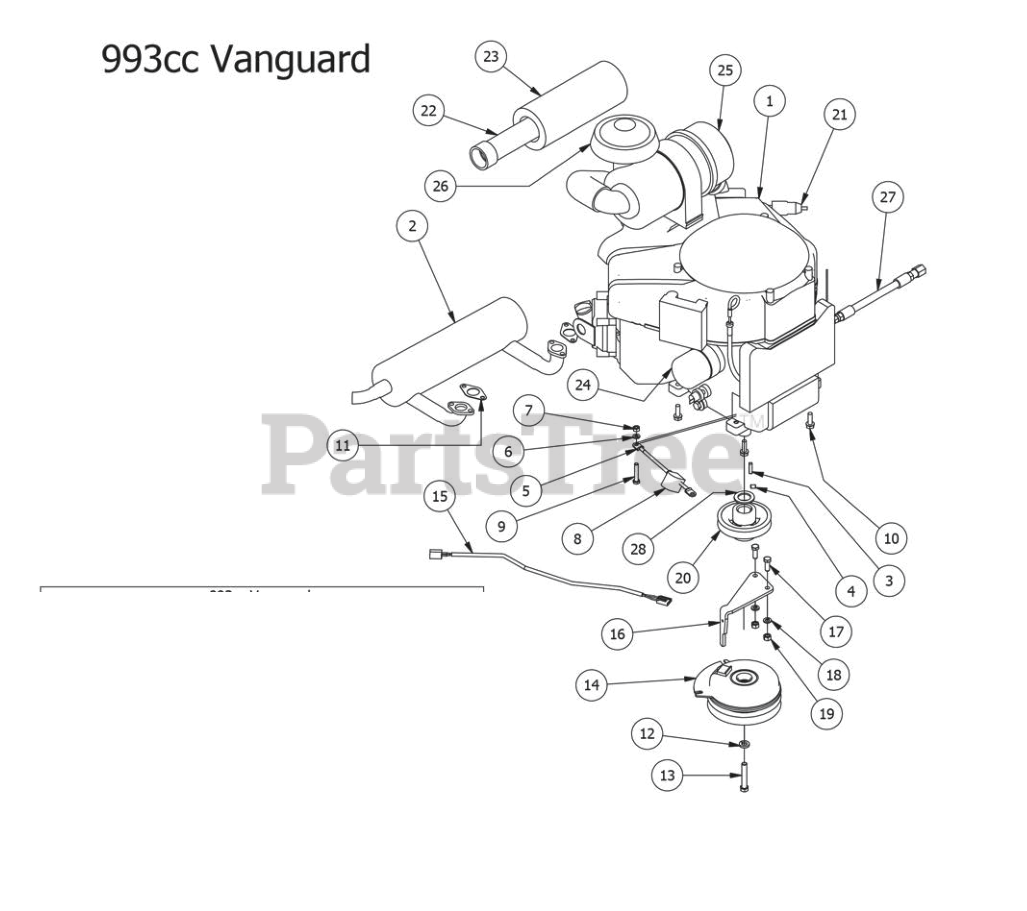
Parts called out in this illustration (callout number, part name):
1	993cc Briggs Vanguard Engine
2	Vanguard Exhaust
3	1/4" x 1" Key
4	5/16 Set Screw
5	Starter to chassis cable
6	5/16" Lock Washer
8	Black Boot For ground cable
9	5/16" x 1 3/4" Hex Bolt
10	3/8 x 1 1/8 bolt
11	Exhaust Gasket
12	7/16" Lock Washer
13	7/16" x 2 1/2" Hex Bolt
14	Clutch Assembly
15	Clutch Pigtail
16	PTO Engager Holder
17	3/8" x 1" Hex Bolt
18	3/8" Lock Washer
19	3/8" Hex Nut
20	4 3/4 Motor Pulley
21	Universal inline Fuel Filter
22	Canister Air Filter- Inner
23	Canister Air Filter- Outer
24	Briggs Oil Filter
25	Complete Canister
26	Rain Cap Fits all Canisters
27	14 mm Oil drain Hose 993cc Vanguard
28	1 1/8" Flat Spacer
